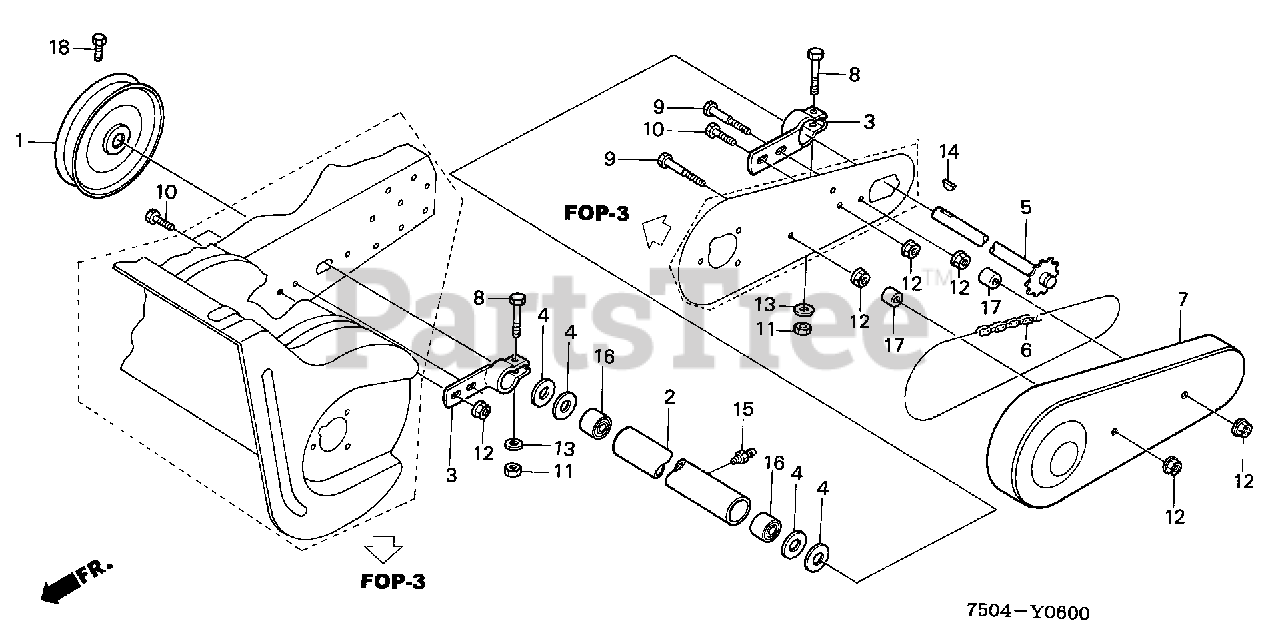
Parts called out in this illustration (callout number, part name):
1	PULLEY, SNOW THROWER
2	HOUSING ASSY., BEARING
5	SHAFT ASSY.
7	GUARD, CHAIN
8	BOLT, HEX. (5/16-18X1 3/4)
9	BOLT, HEX. (3/8-16X2)
10	BOLT, HEX. (3/8-16X1)
11	NUT, HEX. (5/16-18)
12	NUT, LOCK FLANGE (3/8X16)
13	WASHER, LOCK (5/16)
15	FITTING, GREASE
16	BEARING, NEEDLE
18	BOLT, HEX. (8X12)
